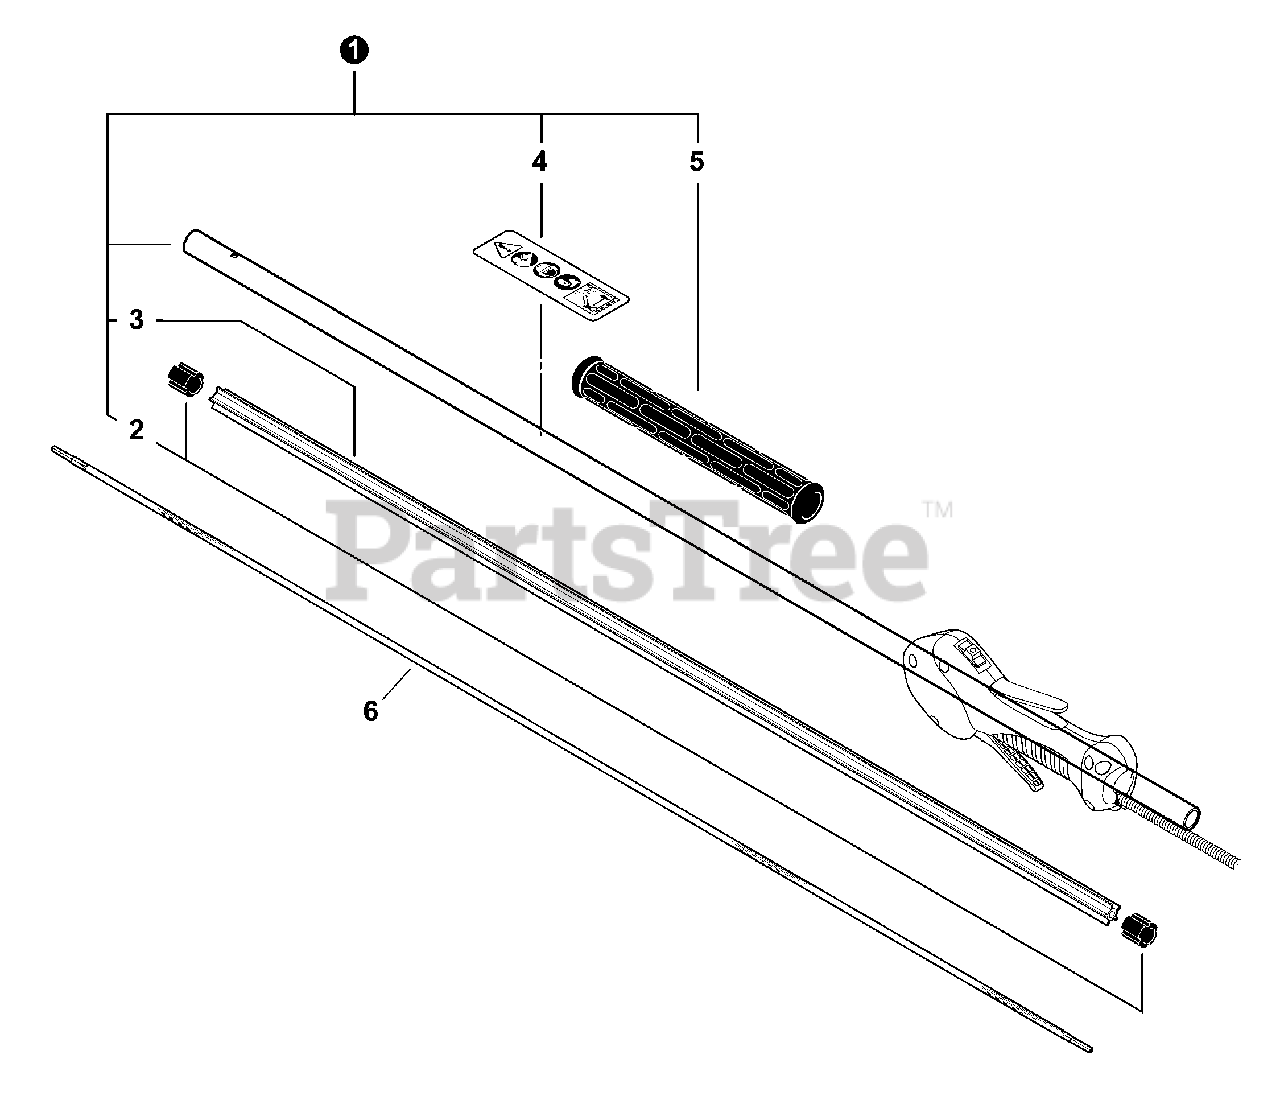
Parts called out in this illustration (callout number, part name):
1	MAIN PIPE ASY
3	LINER - FLEXIBLE
4	LABEL - CAUTION
5	GRIP, HANDLE
6	DRIVESHAFT - FLEXIBLE
